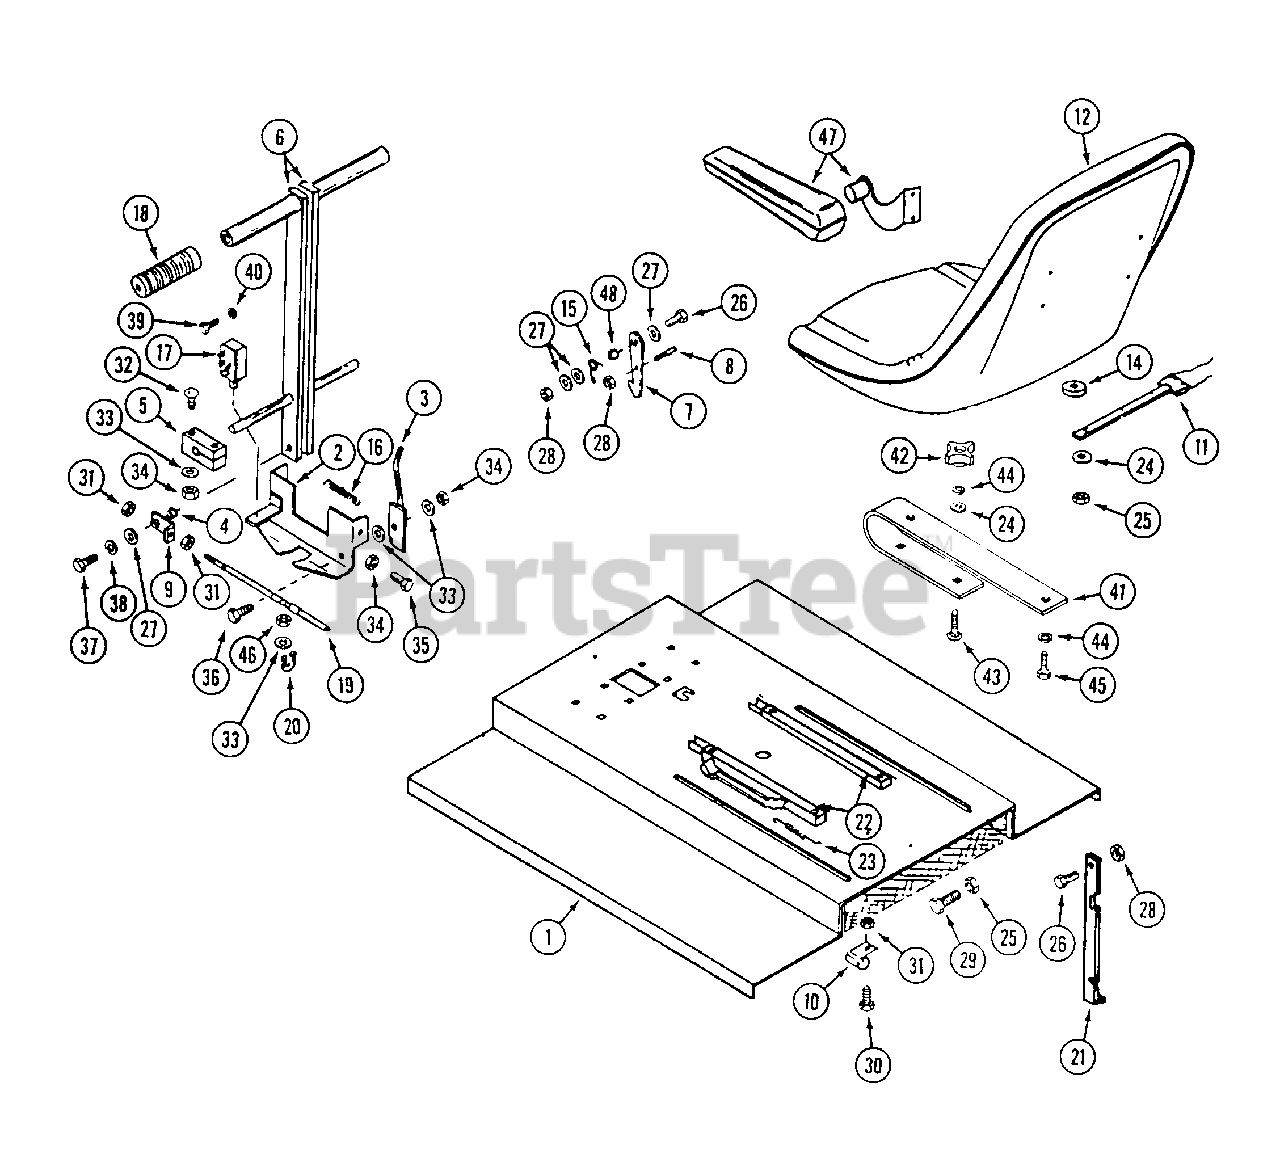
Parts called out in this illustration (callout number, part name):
2	BRACKET - lever lock
3	LATCH - lever lock
4	BUSHING -
5	BEARING - block
6	LEVER - steering
7	LATCH - seat lid
8	BOLT - latch, seat lid
9	BRACKET - steering cable end
10	RETAINER - harness, seat lid
15	SPRING - latch, seat lid
16	SPRING - bracket, lever lock
17	SWITCH - safety
18	GRIP - handle
19	CABLE - steering
20	CLAMP - steering cable
21	PROP - seat lid
22	KIT - seat slide rail (pair)
24	WASHER - 5/16"
25	NUT - 5/16"
26	BOLT - 1/4" - 20 x 1"
27	WASHER - 1/4"
28	NUT - 1/4" - 20 lock
29	BOLT - 5/16" - 18 x 1"
30	SCREW - #10 - 32 x 1/2"
31	NUT - #10 - 32
32	BOLT - 1/4" - 20 x 1-1/2" carriage
33	WASHER - 1/4"
34	NUT - 1/4" - 20 lock
35	BOLT - 1/4" - 20 x 3/4"
36	BOLT 1/4" - 20 x 2"
37	BOLT - 1/4" - 20 x 3/4"
38	LOCKWASHER - 1/4"
39	SCREW - #10 - 32 x 3/8"
40	LOCKWASHER - 3/16"
41	SPRING - seat
43	BOLT - carriage 5/16" - 18 x 1-1/4"
44	LOCKWASHER - 5/16"
45	BOLT - 5/16" - 18 x 1"
46	NUT - 1/4" - 20
47	KIT - arm rest
